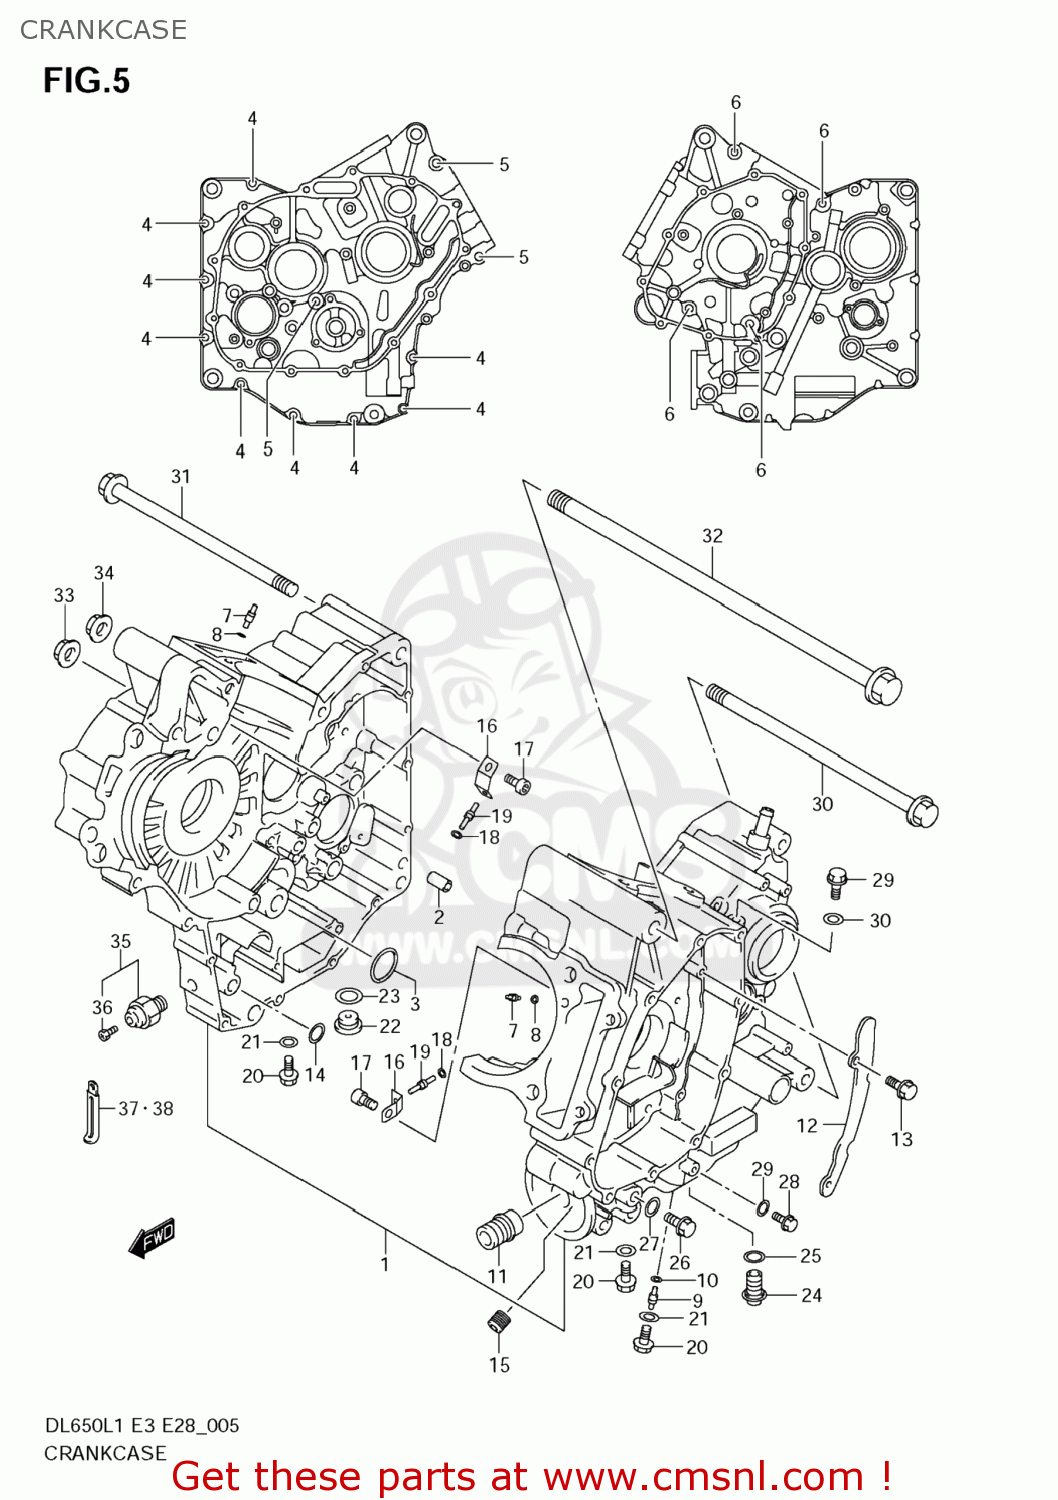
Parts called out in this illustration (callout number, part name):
1	CRANKCASE SET
2	PIN(8.4X11X20)
3	O RING(D:2.4,ID:15.8)
4	BOLT
5	BOLT
6	BOLT
7	JET,AIR(14)
8	O RING(D:1.2,ID:4)
9	JET,AIR(14)
10	O RING(D:1.2,ID:4)
11	UNION,OIL STAND
12	PLATE,OIL SEPARATOR
13	BOLT
14	O RING(D:1.9,ID:12.6)
15	JET,OIL GALLERY(3.6)
16	PLATE,PISTON COOLING JET
17	BOLT(6X12)
18	O RING(D:1.2,ID:4)
19	JET(13)
20	BOLT
21	GASKET(8.2X14X1) (NAS)
22	PLUG,16X8
23	GASKET(16X22X2) (NAS)
24	PLUG(12X20)
25	GASKET(12.1X16.2X3.7) (NAS)
26	PLUG(12X10)
27	GASKET(12X17X1) (NAS)
28	BOLT
29	GASKET(5.8X13X1.2) (NAS)
30	BOLT(10X275)
31	BOLT(10X225)
32	BOLT(12X310)
33	NUT
34	NUT
35	SWITCH ASSY,OIL PRESSURE
36	BOLT,OIL PRESSURE SWITCH
37	CLAMP(L:45)
38	CLAMP(L:80)
